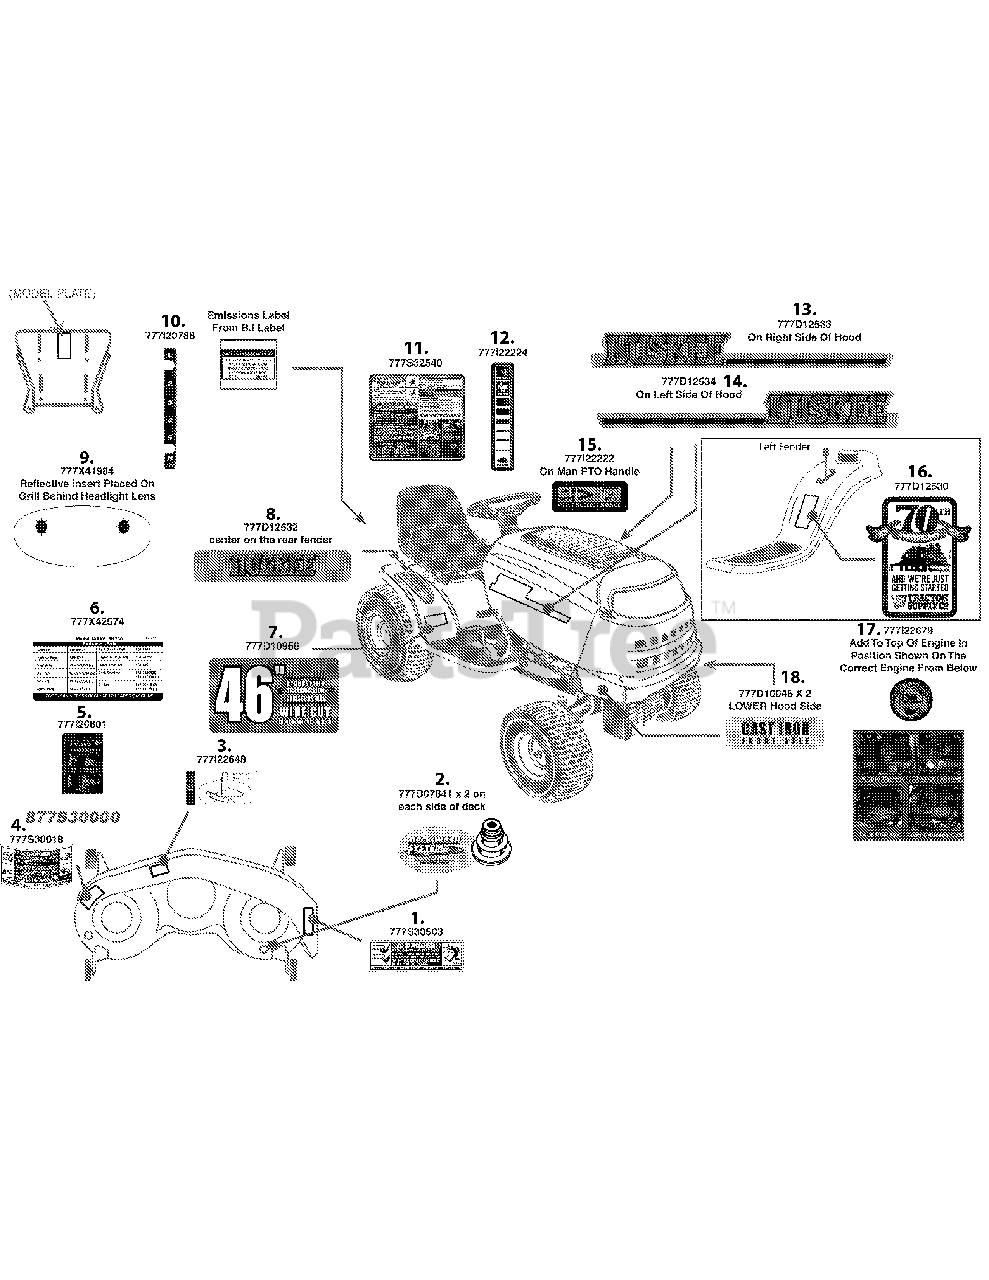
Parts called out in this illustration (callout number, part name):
1	LABEL-DANGER CHUTE
2	LABEL-RIDER DECK
3	LABEL-DECK BELT ROUTE
4	LABEL-DECK SAFETY
5	LABEL-HITCHPLATE
6	LABEL-RIDER PARTS LIST X615H
7	LABEL-RIDER FENDER:46" HUSKEE
8	LABEL-REAR FENDER HUSKEE
9	LABEL-RIDER 1&5 STYLE GRILL
10	LABEL-SIDE FENDER
11	LABEL-RIDER SAFETY HYD W/CRSE
12	LABEL-DASH RH THROTTLE /CHOKE
13	LABEL-RIDER HOOD RH HUSKEE
14	LABEL-RIDER HOOD LH HUSKEE
15	LABEL-PTO HANDLE
16	LABEL-RIDER FENDER TSC
17	LABEL-CHECK ENG OIL
18	LABEL-RIDER LOWER HOOD
